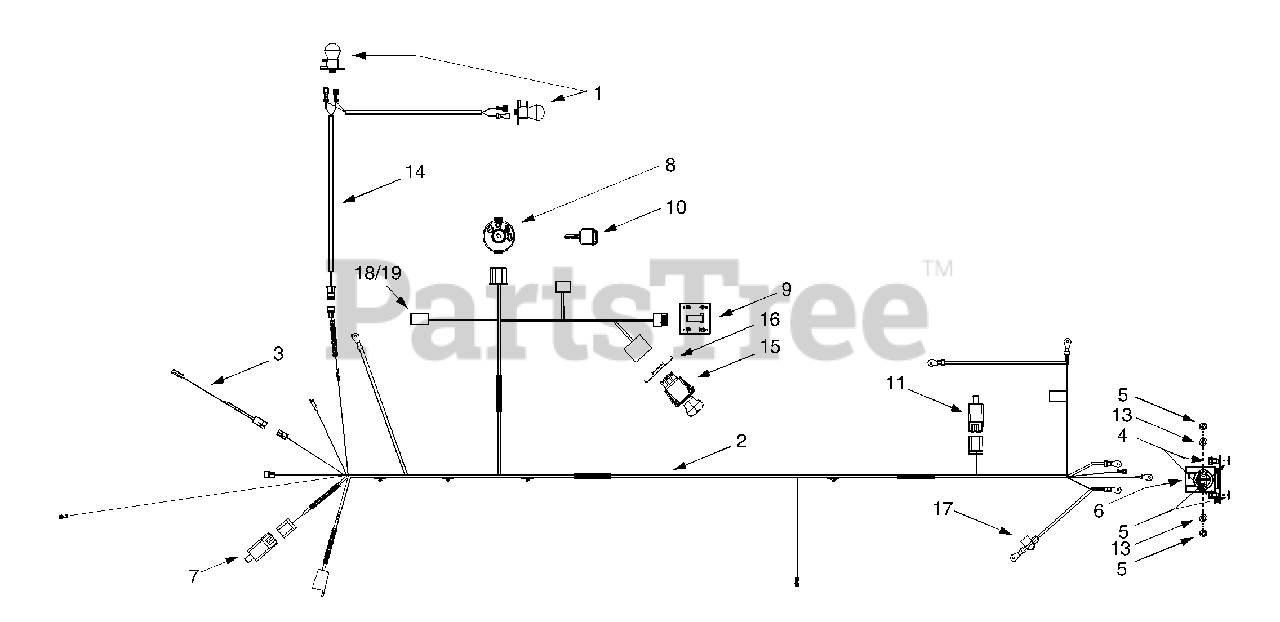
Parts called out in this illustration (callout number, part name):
1	Bulb/Socket Headlight Assembly
2	Wiring Harness w/o
3	Harness Adapter, #18 x 5
4	Self Tapping Screw, 1/4-20 x .5
5	Hex Nut, 1/4-20
6	Solenoid, 12-volt, 100 Amp
7	Snap Mount Safety Interlock Switch (Brake)
8	Ignition Switch
9	Indicator Monitor / Hour Meter
10	Ignition Key
11	Safety Plunger Switch (Seat)
13	Lock Washer, 1/4
14	Headlight Harness
15	Electric PTO Switch
16	Retainer Bracket
17	Positive Terminal Cover (Boot)
18	Fuse Holder
19	20-amp Fuse
